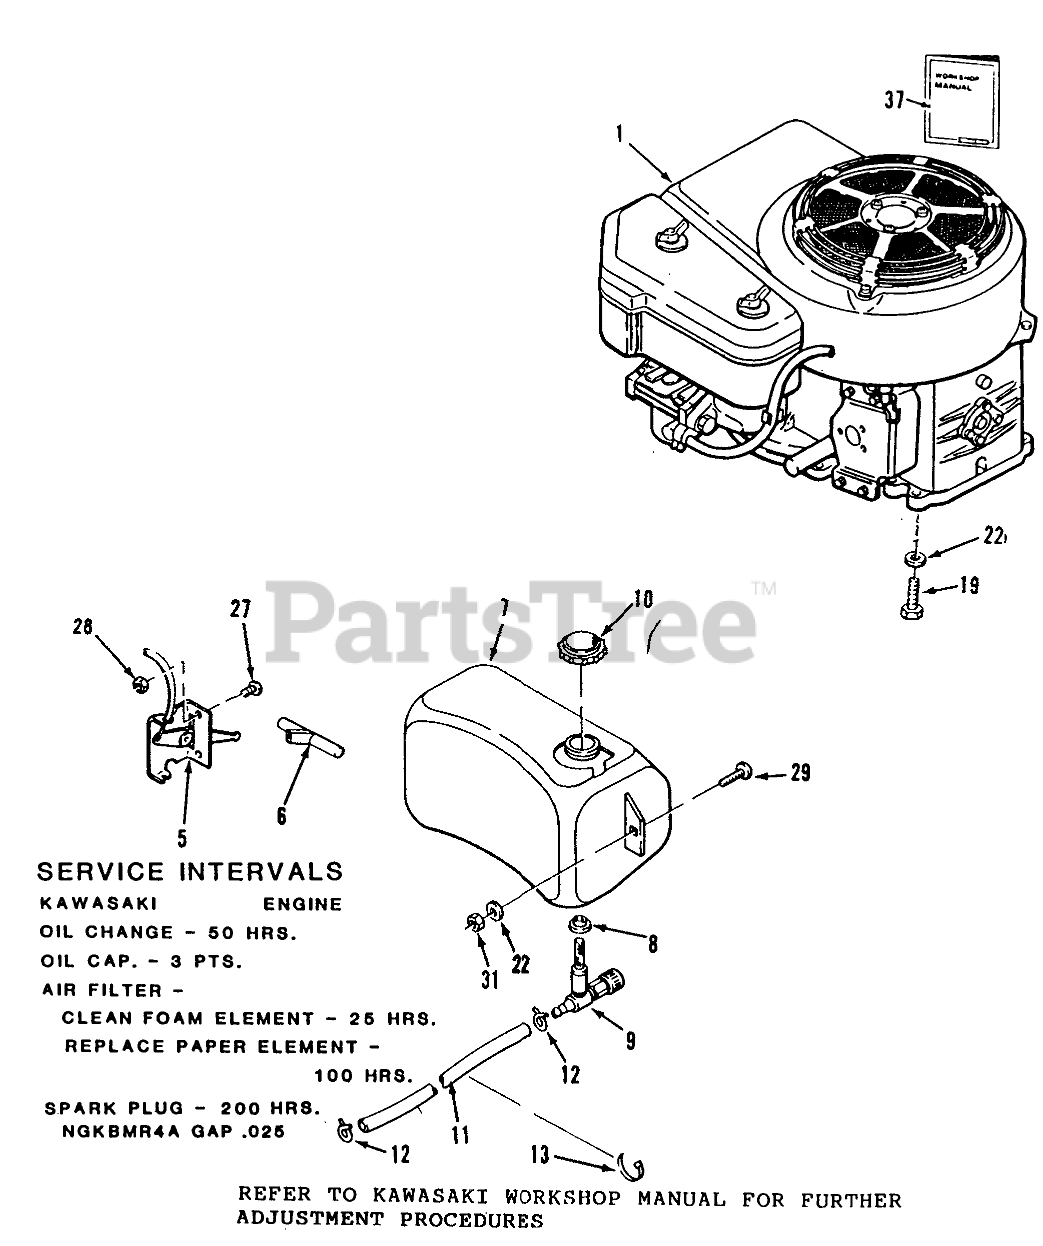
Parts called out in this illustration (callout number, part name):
1	Engine-12HP-Kawasaki FB460V
5	THROTTLE-CONTROL
6	KNOB-CONTROL
7	Fuel Tank
8	BUSHING
9	VALVE-FUEL
10	CAP GAS
11	Fuel Line
12	Clamp
13	PLASTIC TIE
19	Bolt
22	WASHER 5/16 SAE
27	Screw
28	Nut
29	Bolt
31	Nut
37	Kawasaki FB460V Workshop Manual
